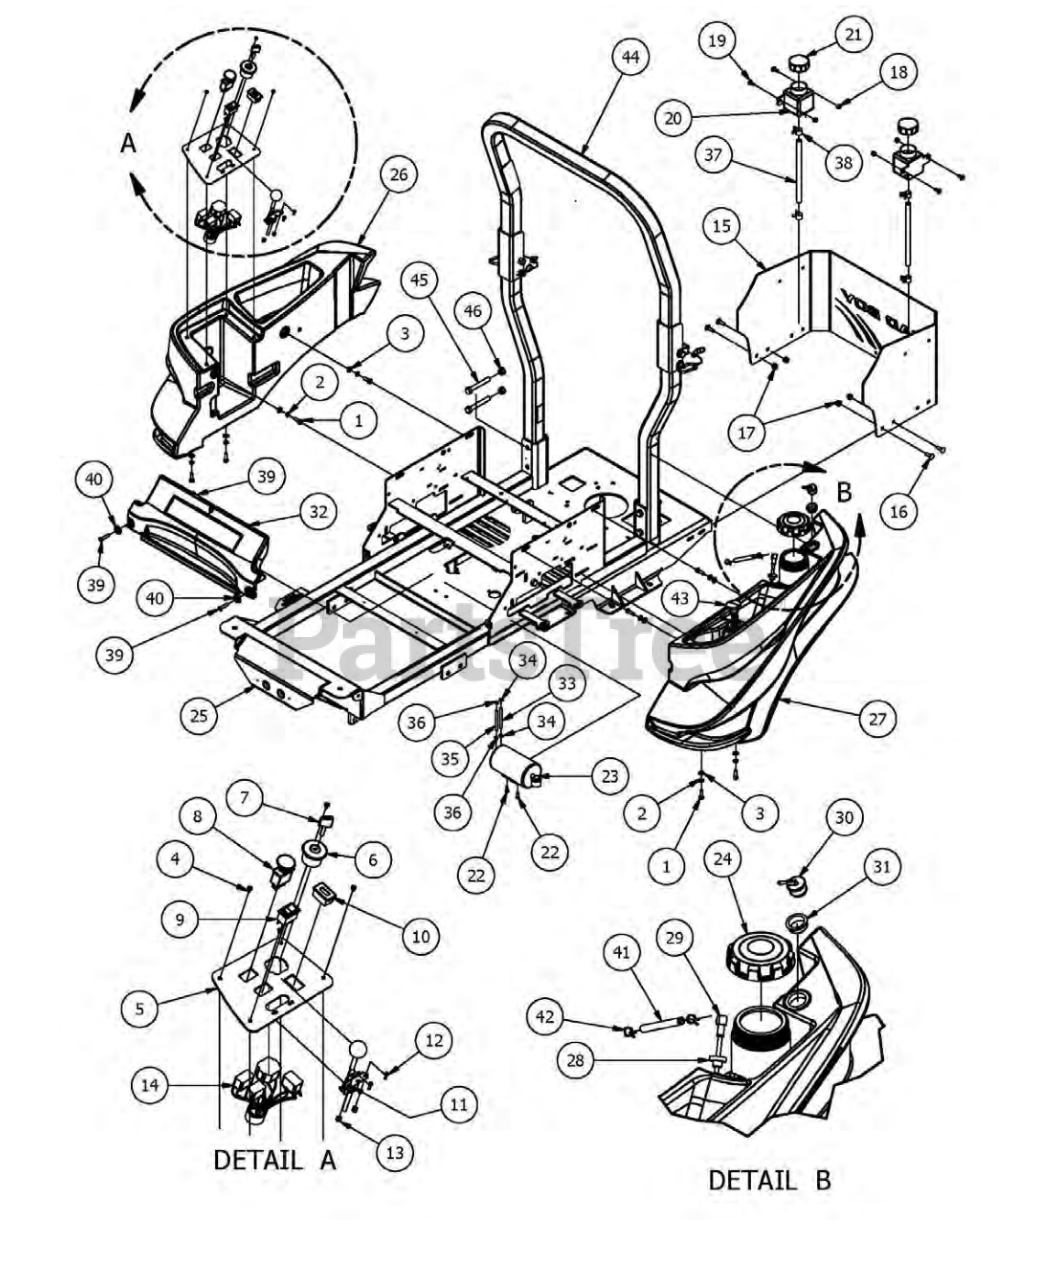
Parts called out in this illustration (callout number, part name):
1	5/16" x 1" Bolt
2	5/16" Lock Washer
3	5/16" Flat Washer
4	10-32 x 3/8" Button Socket Head Bolt
5	Control Panel
6	Ignition Switch
7	Ignition Key
8	PTO Engager
9	Rocker Deck Lift Switch 2011
10	Tachometer
11	Throttle Lever Assembly
12	10-24 X 5/8 BS Button Head Bolt
13	10-24 Nylon Insert Locknut
14	Wire Harness
15	Maveric Rear Cover
16	5/16" x 1" Carriage Bolt
17	5/16-18 Nylon Flange Nut
18	1/4" Nylock Nut
19	1/4" x 3/4" Carriage Bolt
20	350ml Expansion Tank
21	Hydraulic Tank Cap
22	M6-1.0 X 16MM Hex Bolt
23	Carbon Canister
25	2016 Maverick Frame
26	Right Fuel Tank
27	Left Fuel Tank
28	Pick-Up Grommet
30	Rollover Valve
31	Rollover Valve Grommet
32	Front Cover
33	1/4" Vinyl Tubing
34	1/4" Hose Clamp
35	3/16 Vinyl Tubing
36	3/16" Vinyl Hose Clamp
37	3/8" Clear Hose
38	3/8" Hose Clamp
39	5/16-18x1.5 torx cutter-Black
40	1/2" Flat Washer Flat Black
41	1/4" Fuel Line Hose
42	1/4 Fuel Hose Clamp
43	Fuel Gauge w/Grommet
45	1/2-13 x 3 1/2 GR 5 Hex Bolt
46	1/2" Center Lock Nut
